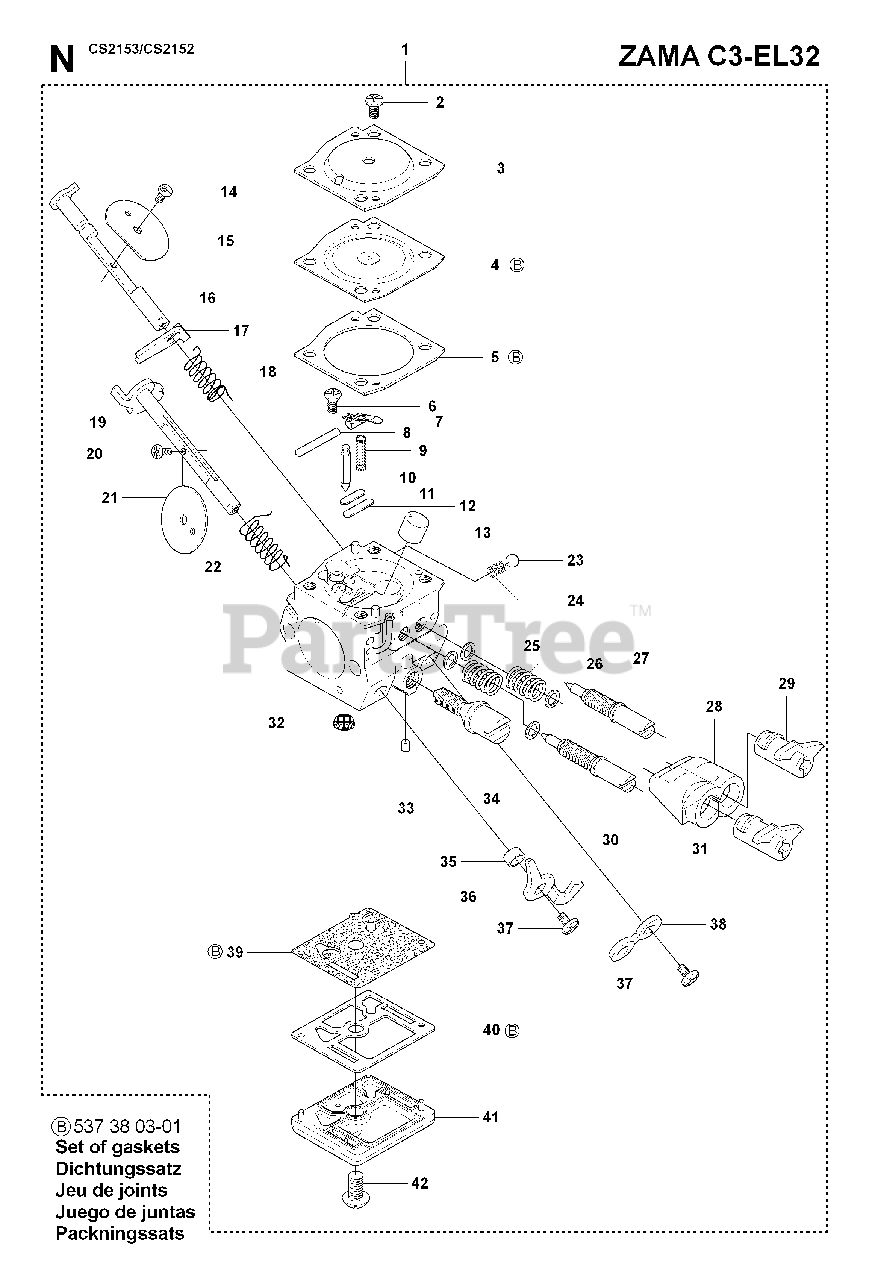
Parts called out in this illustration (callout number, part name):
1	CARBURETOR
4	DIAPHRAGM
8	PIN FULCRUM
15	CHOKE FLAP
16	CHOKE SHAFT
17	THROTTLE LOCK
19	THROTTLE SHAFT
21	THROTTLE FLAP
26	SPRING
29	LIMITER CAP
30	LOW SPEED NEEDLE
31	LIMITER CAP
34	IDLE SCREW
35	BUSHING *
39	PUMP DIAPHRAGM
B	GASKET SET
